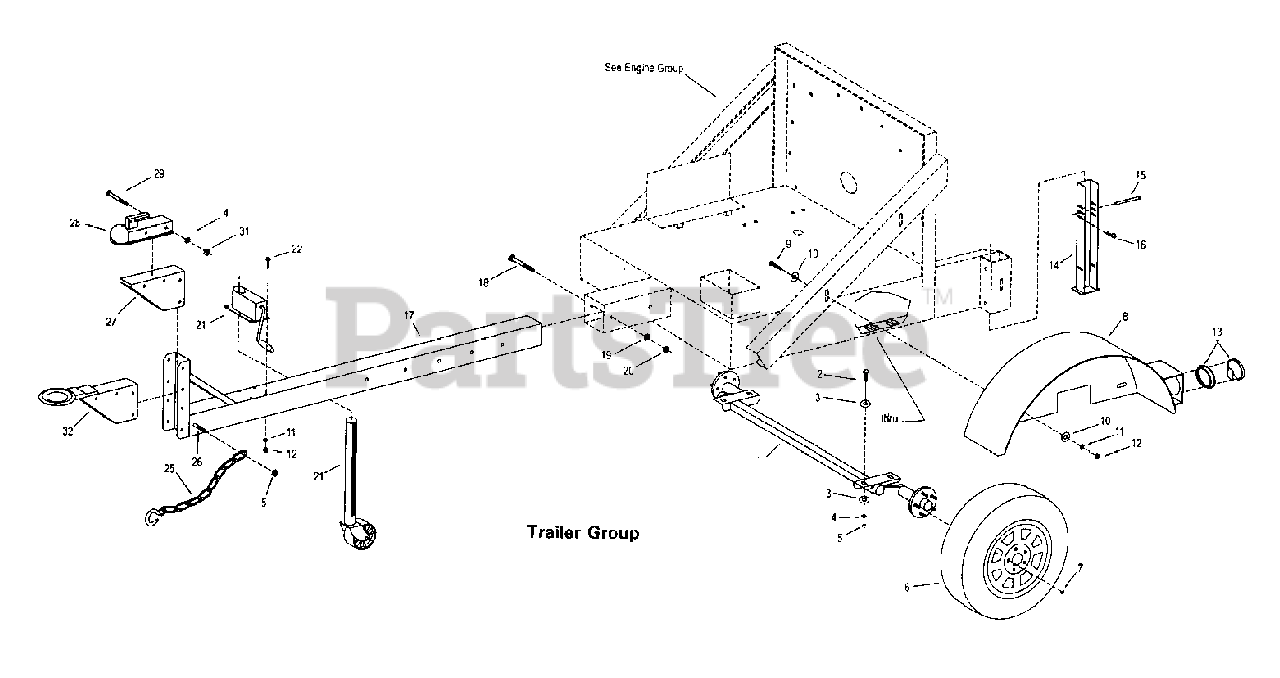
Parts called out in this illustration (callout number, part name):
1	Torflex Axle
2	1/2-13 x 1-1/4" Hex Bolt
3	1/2 Flat Washer
4	1/2 Lock Washer
5	1/2-13 Hex End Lock Nut
6	F78 x 15 Tire and Wheel Assembly
7	1/2-20 Lug Nut
8	Fender - Left Side
9	3/8-16 x 1" Hex Bolt
10	3/8 Flat Washer
11	3/8 Split Lock Washer
12	3/8-16 Hex Nut
13	Tail Lamp (w/Rubber Mounting Ring)
14	Support Leg
15	3/8 x 4" Clevis Pin
16	Bridge Pin
17	Draw Bar - Swing Jack Style
18	5/8 x 4-1/2" Hex Bolt
19	5/8 Split Lock Washer
20	5/8 Lock Nut
21	Jack, Trailer Support Swing Away Style
22	3/8-16 x 5" Hex Bolt
25	Chain, Safety w/1 S-Hook
26	HHCS, 1/2-13 x 5 YZ
27	Ball Hitch Mount, Black
28	Ball Hitch
29	1/2-13 x 3-1/2" Hex Bolt
31	1/2 Lock Nut
32	Pintle Ring (Optional)
36	Chain, Nozzle Retainer 1/2 x 12"
